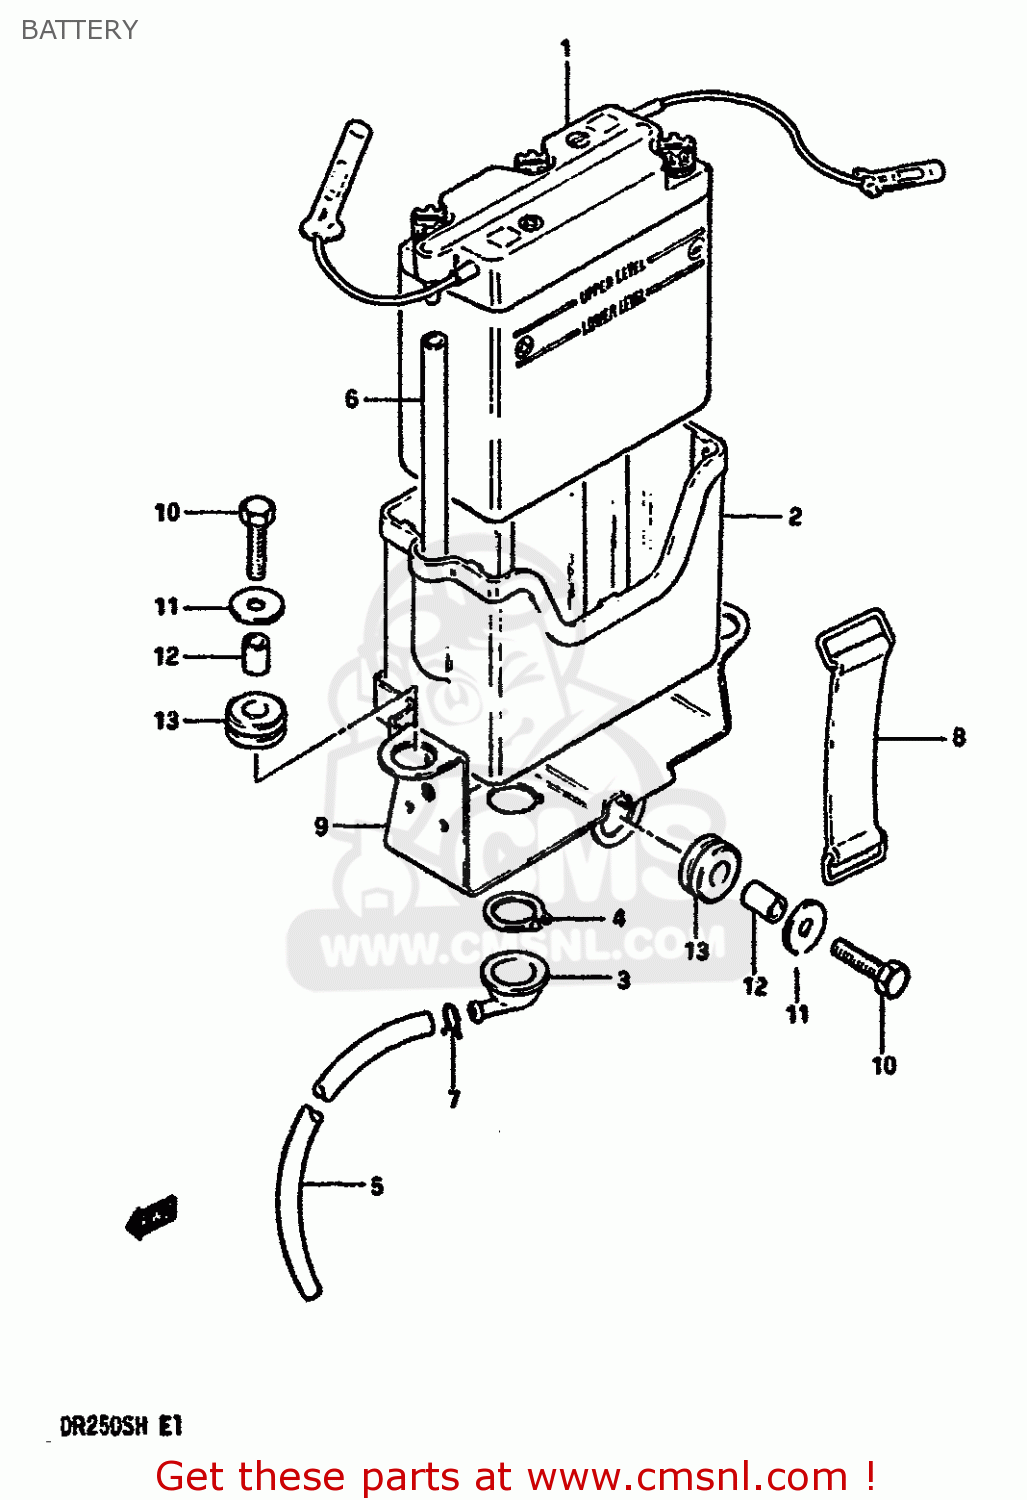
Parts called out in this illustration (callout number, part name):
1	BATTERY (6V, 4AH)
2	CASE,BATTERY
3	FUNNEL,BATTERY EXHAUST
4	CIRCLIP
5	HOSE,BATTERY EXHAUST
6	HOSE,BATTERY EXHAUST
7	CLIP
8	BAND
9	HOLDER,BATTERY
10	BOLT
11	WASHER (6.5X20X1.2)
12	SPACER(6.1X9X7.5)
13	CUSHION
